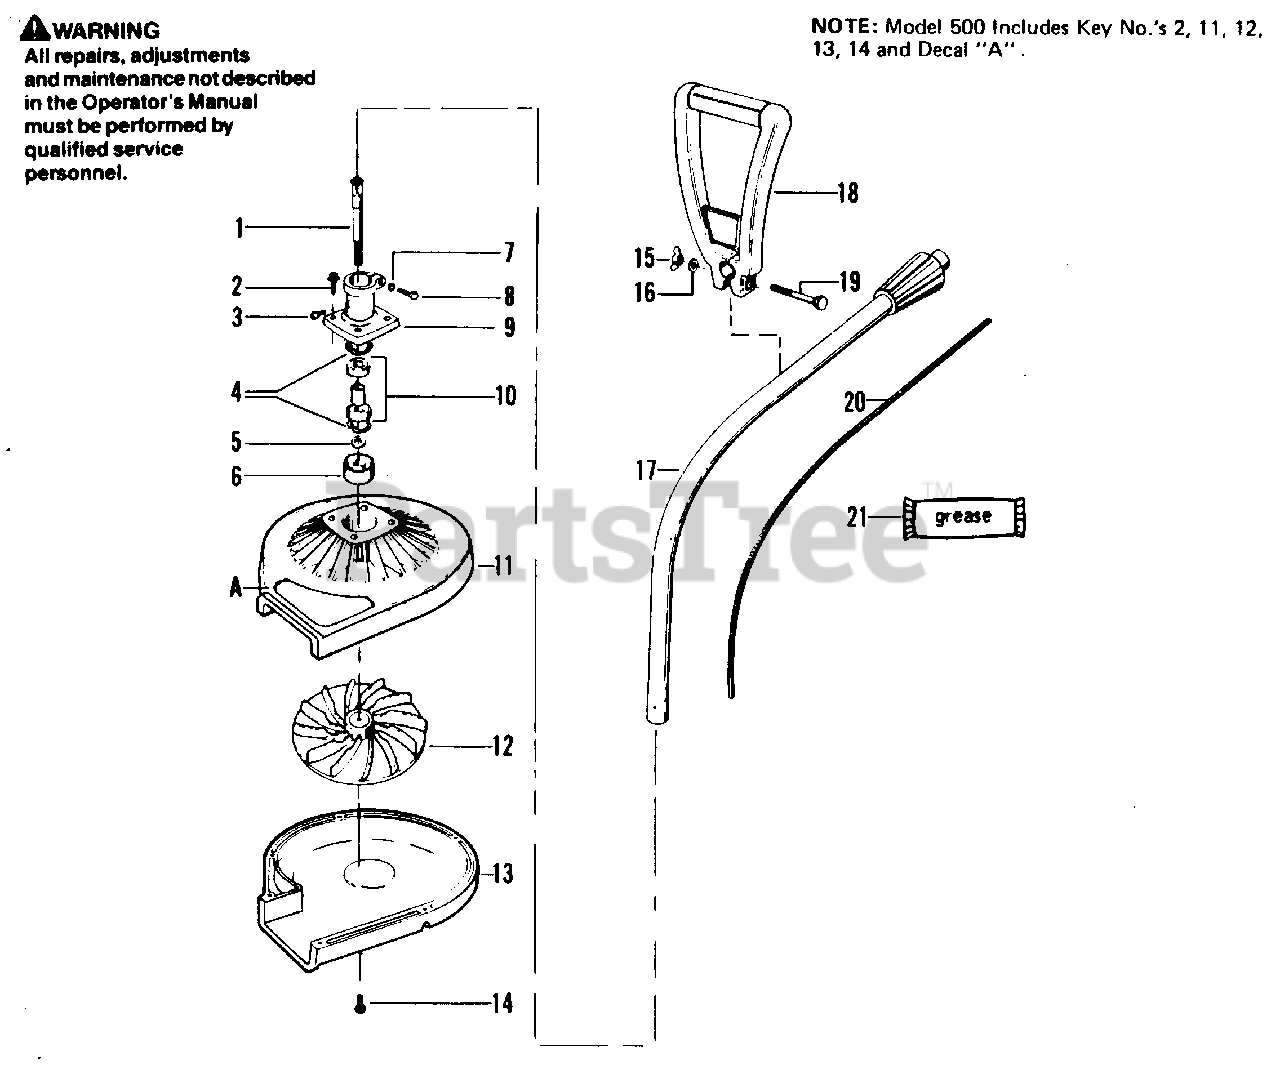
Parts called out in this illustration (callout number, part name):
1	Arbor Shaft
2	Screw - Bearing Housing 1/4 Plastite
3	Screw - Tapping # 10-16-1/4
4	Retaining Ring
5	Washer - Dust Cup
6	Dust Cup
7	Washer - 1/4 - 20 Interlock
8	Screw - 1/4 - 20x 1 (Hex Head)
9	Bearing Housing Ass'y (incl, #'s 1,4-8 & 10)
10	Bearings and Spacer
11	Housing - Upper Impeller
12	Impeller
13	Housing - Lower Impeller
14	Screw - Impeller Housing Ass'y # 10 Plastite
15	Wing Nut - "D" Handle
16	Washer - "D" Handle
17	Drive Shaft Ass'y (incl. # 20)
18	"D" Handle
19	Screw - "D" Handle
20	Flexible Drive Shaft
21	Flex Shaft Lube
A	Decal - Warning/Product
